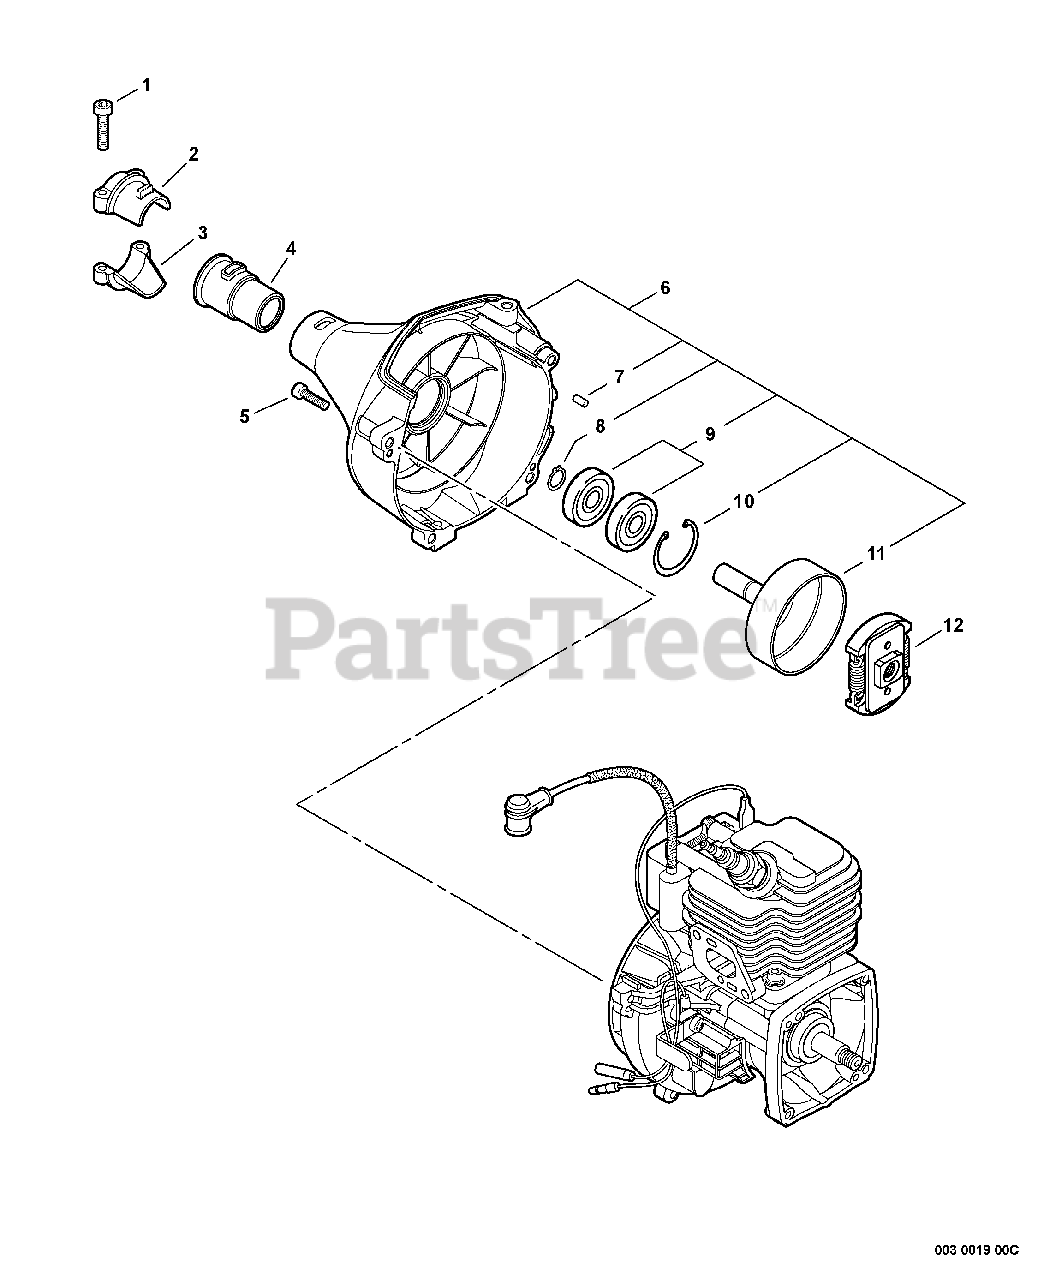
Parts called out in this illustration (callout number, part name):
1	BOLT, TORX 5×20
2	HOLDER, MAIN PIPE - UPPER
3	HOLDER - LOWER
4	CUSHION Ø25
5	BOLT, TORX 4×16
6	FAN CASE ASSY
7	PIN, LOCATING 4
8	RING, RETAINING - 12
9	BEARING, BALL 6001
10	RING, SNAP 28
11	DRUM, CLUTCH
12	CLUTCH ASSY
